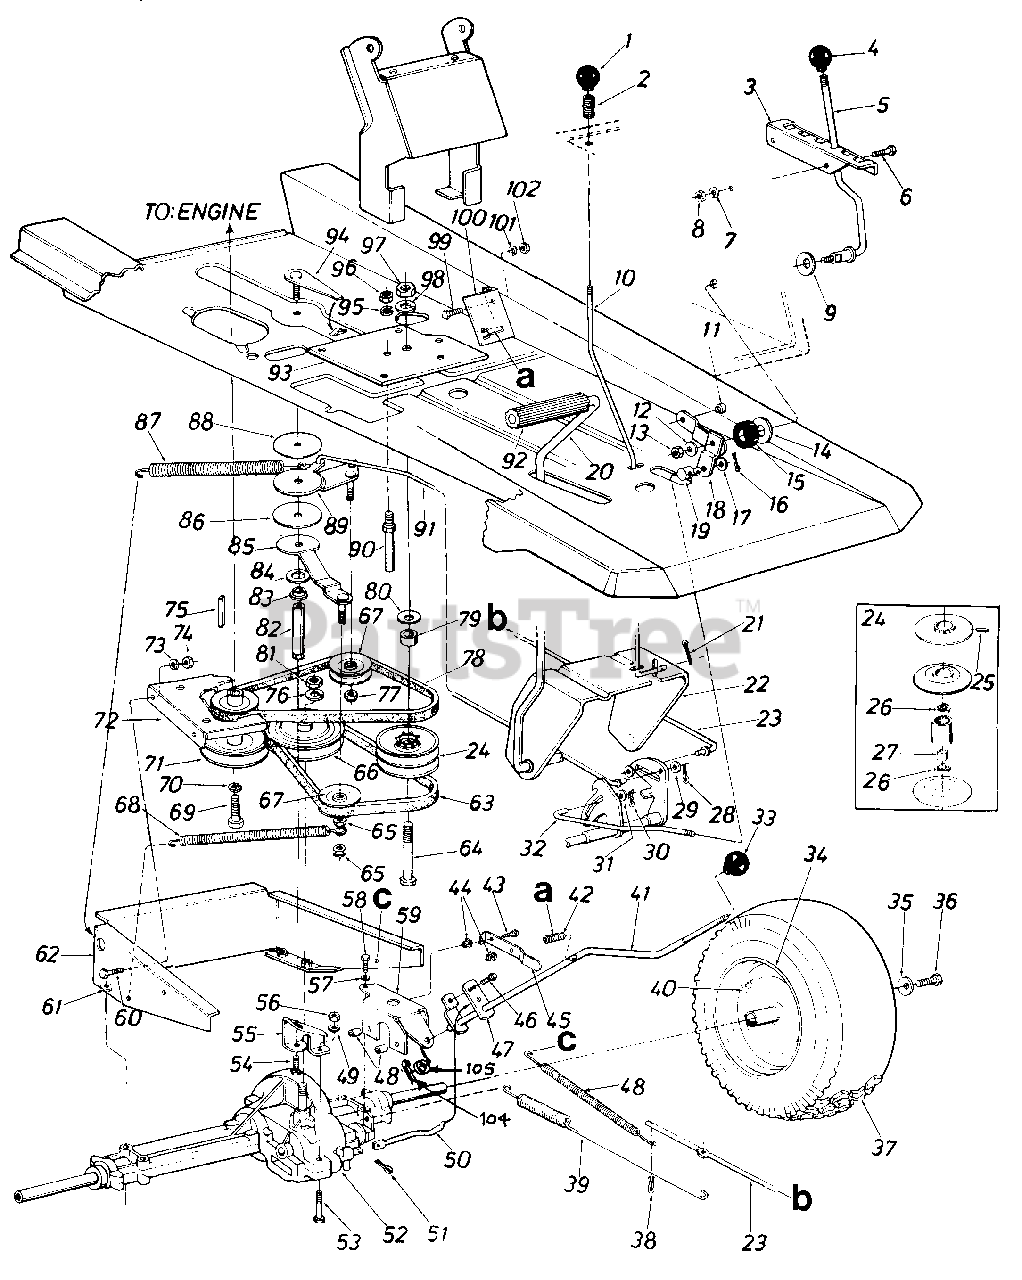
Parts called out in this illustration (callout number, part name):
1	Ball Knob 1/4-20 Thd. 1.25"
2	Compression Spring
5	Speed Control Lever
6	Truss Mach. Scr. 5/16-18 x .75 " Lg .
7	L-Wash. 5/16" I.D.
8	Hex Nut 5/16-18 Thd.
9	Bell-Wash. .345" I.D. x .88"
10	Brake Locking Rod
12	Bell-Wash .345" I.D. x .08"
13	Hex Cent. L-Nut 5/16-18 Thd.
14	Fl-Wash. .50" I.D. x 1.5" O.D.
15	Rubber Wash. .50" I.D. x 1.25" O.D.
16	Intern. Cotter Pin 1/2" Dia.
17	Fl-Wash. .34" I.D. x .68" O.D.
18	Speed Control Lever Brkt. Ass'y.
19	Ferrule Engagement
20	Clutch/Brake Pedal Ass'y.
21	Cotter Pin 3/32" Dia. x .75"
22	Clutch/Brake Pedal Ass'y.
23	Brake Rod
24	Variable Speed Pulley Ass'y.
25	Spring Pin Spir. 5/32" Dia. x .62" Lg.
26	Ball Brg. .50" I.D. x 1.38"
27	Spacer .50" I.D. x 1.00" Lg.
28	Cotter Pin 1/8" Dia. x 1.25"
29	Fl-Wash. .34" I.D. x .60" O.D.
30	Intern. Cot-Pin 5/16" Dia.
31	Fl-Wash. .34" I.D. x .60" O.D.
32	Speed Control Rod
33	Ball Knob
35	Bell-Wash. .345" I.D. x .88"
36	Hex L-Bolt 5/16-24 x .75" Lg.
38	Cotter Pin 1/8" Dia. x 1.25"
39	Extension Spring 17" Lg.
40	Air Valve
43	C Sink AB S-Tap Scr. #8 x .50" Lg.
44	Push-in Nut #10
45	Spring Switch
46	Hex Bolt 1/4-20 X .50" Lg.
47	Shift Lever Adjusting Link
48	Spacer.256" I.D. x .87" Lg.
49	L-Wash. 1/4" I.D.
50	Shift Rod
51	Intern. Cotter Pin
52	Transaxle
53	Hex Bolt 1/4-20 X 1.75" Lg.
54	Hex Bolt 3/8-24 x .751' Lg.
55	Torque Rod Bracket
56	Hex Nut 1/4-20 Thd.
57	L-Wash. 1/4" I.D.
58	Self-Tap Mach. Scr. Type "C" 1/4-20 X 1.37" Lg.
59	Shift Lever Support Brkt.
60	Hex Bolt 1/4-20 X 1.OO" Lg.
61	Hex Nut 5/16-18 Thd.
62	Transaxle Support Ass'y.
63	V-Belt 5/8 x 38.0" Lg.
64	Hex Bolt 1/2-13 x 4" Lg.
65	Hex Ins. L-Nut 3/8-24 Thd.
66	5/8 V-Pulley .500" I.D. x 6"
67	V-Belt Idler .38" I.D. x 3.06"
68	Ext. Spring .50" O.D. x 6.37"
69	Hex Bolt 7/16-20 x 1.00" Lg.
70	L-Wash. 7/16" I.D.
71	Engine Pulley .500" O.D. & 3.56" O.D.
72	Upper Eng. Belt Guard
73	L-Wash. 1/4" I.D.
74	Hex Nut 1/4-20 Thd.
75	Sq.-Key 1/4" X 2.00" Lg.
76	L-Wash. 1/2" I.D.
77	Hex Ins. L-Nut 3/8-24 Thd.
78	V-Belt 5/8 x 35.0" Lg.
79	Spacer .501" I.D. x .775" Lg.
80	Bell-Wash. .505" I.D. x 1.00"
81	Hex Nut 1/2-13 Thd.
82	Torque Rod
83	Flange Bearing .378
84	Fl-Wash. .640" I.D. x 1.24'
85	Idler Bracket Ass'y.
86	Thrust Wash. .635" I.D.
87	Extension Spring 8.0" Lg.
88	Thrust Wash. .385" I.D.
89	Idler Bracket Ass'y. For Clutch
90	Belt Guard Pin 1/4" Dia.
91	Clutch Rod
92	Foot Pad
93	Mounting Bracket Variable Pulley
96	Hex Nut 1/4-20 Thd.
97	Hex Nut 1/2-13 Thd.
98	L-Wash. 1/2" I.D.
99	Hex Bolt 5/16-18 x .75" Lg.
100	Shift Lever Spring Brkt.
101	L-Wash. 5/16" I.D.
102	Hex Nut 5/16-18 Thd.
104	Cotter Pin 3/32" Dia.
105	Fl. Wash. .469" I.D. x.88" O.D.
